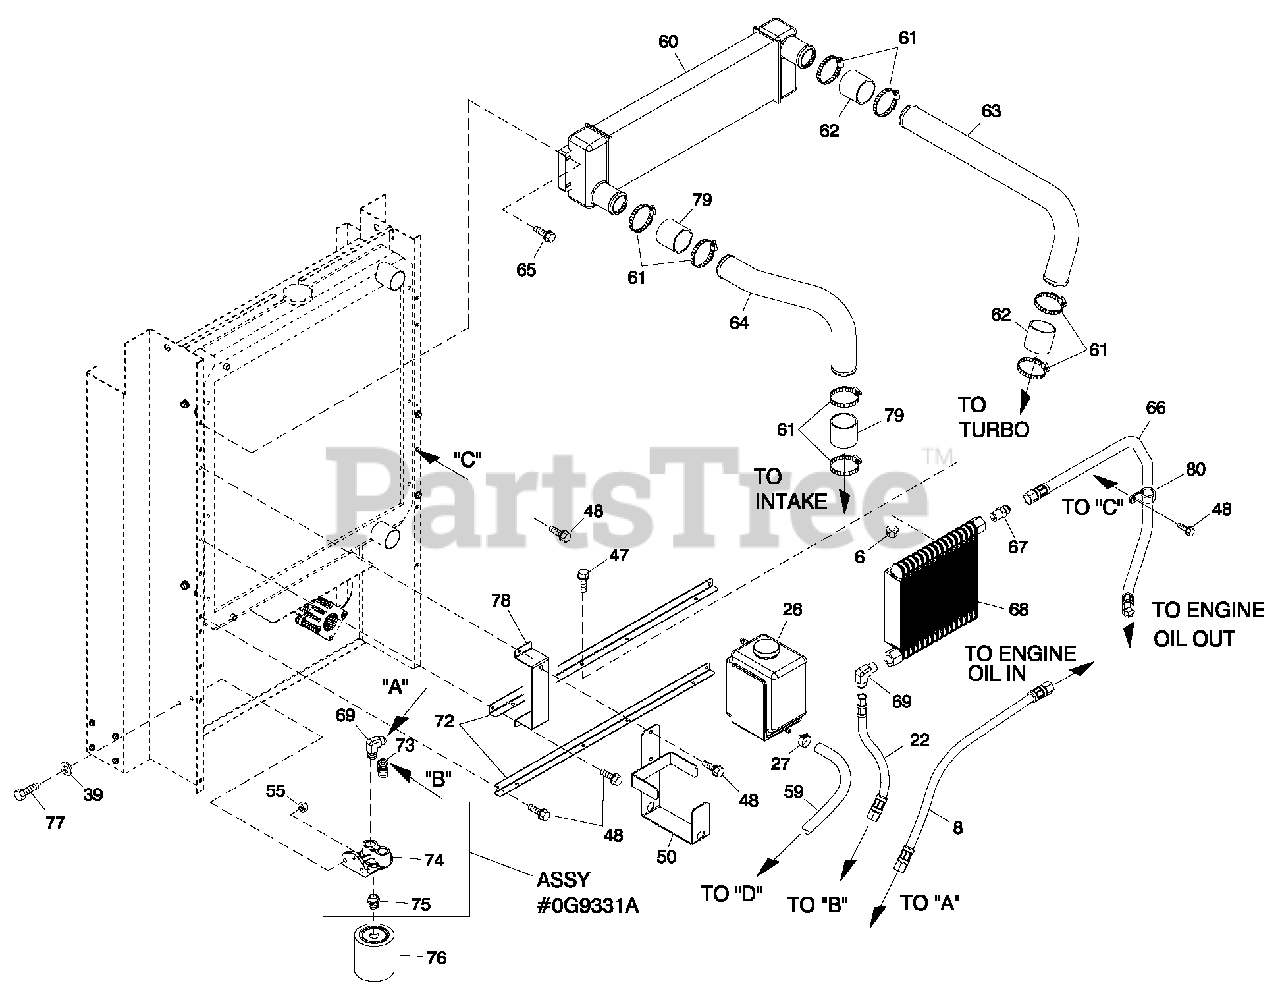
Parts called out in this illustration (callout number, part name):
8	OIL LINE REMOTE FILTER/ENGINE
22	OIL LINE REMOTE COOLER/FILTER
27	CLAMP HOSE BAND 1/4
39	WASHER FLAT 5/16-M8ZINC
47	SCREW HHFC M6-1.0X 20G8.8
48	SCREW THF M6-1 X 16 N WA Z/JS
50	BRACKET COOLANT TANK
55	NUT HEX LOCK M8-1.25 NY INS
59	HOSE 9/32 ID (36"LG)
60	CAC 504W X 152H X 50D 2.4L G2
61	CLAMP CNST TENSION 1.75-2.625
62	HOSE 2"IDX 3.0"LG
63	TUBE CAC IN G2 TURBO
64	TUBE CAC OUT G2 TURBO
65	SCREW THF M6-1 X 30 N WA DELTA
66	OIL LINE REMOTE ENG/COOLER
67	ADAPTOR 1/2 NPT X 37JIC 3/4-16
68	COOLER OIL 2.4LG2 TURBO
69	ADAPTER 90D JIC37 1/2NPT X 3/4
72	MOUNT OIL COOLER 2.4LG2
73	ADAPTER 45D JIC37 1/2NPT X 3/4
74	MOUNT REMOTE OIL FILTER 2.4 G2
75	NIPPLE-OIL FILTER
76	FILTER 1.5L/2.4L G2 OIL
77	SCREW HHC M8-1.25X25 C8.8
78	ASSY PCB LCL SENSOR (USE WITH I/N 16, P/N 0H1827 ONLY)
80	NUT FLANGE M6-1.0 NYLOK
